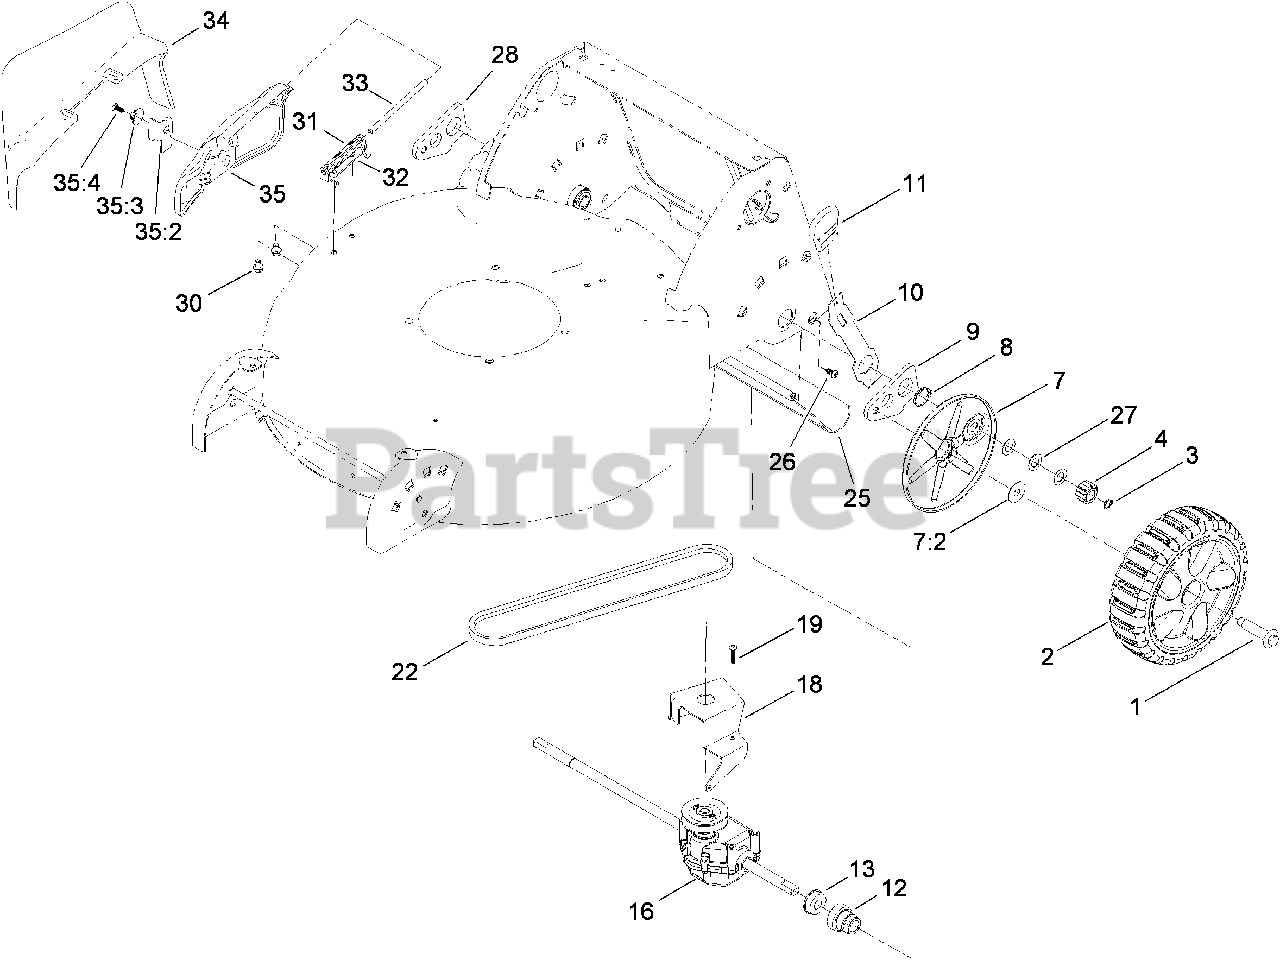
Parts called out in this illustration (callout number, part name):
1	BOLT-SHOULDER
2	REAR WHEEL ASM
3	RING-RETAINING
4	PINION
7	WHEEL COVER ASM
7:2	WASHER-STEPPED
8	RING-RETAINING
9	ARM-REAR PIVOT, LH
10	ARM-SPRING, REAR
12	RETAINER-BEARING, HOC
13	BEARING-BALL
16	TRANSMISSION ASM
18	BRACKET-TRANSMISSION
19	SCREW-PLASTITE
25	SHIELD-TRAILING
26	SCREW-PTH
27	WASHER-PLAIN
28	ARM-REAR PIVOT, RH
30	SCREW-HWH
31	SPRING-TORSION
32	BRACKET-COVER
33	ROD-COVER
34	CHUTE-DISCHARGE, SIDE
35	DISCHARGE DOOR ASM
35:2	LATCH-DOOR
35:3	CAP-DOOR
35:4	SCREW-PLASTITE
